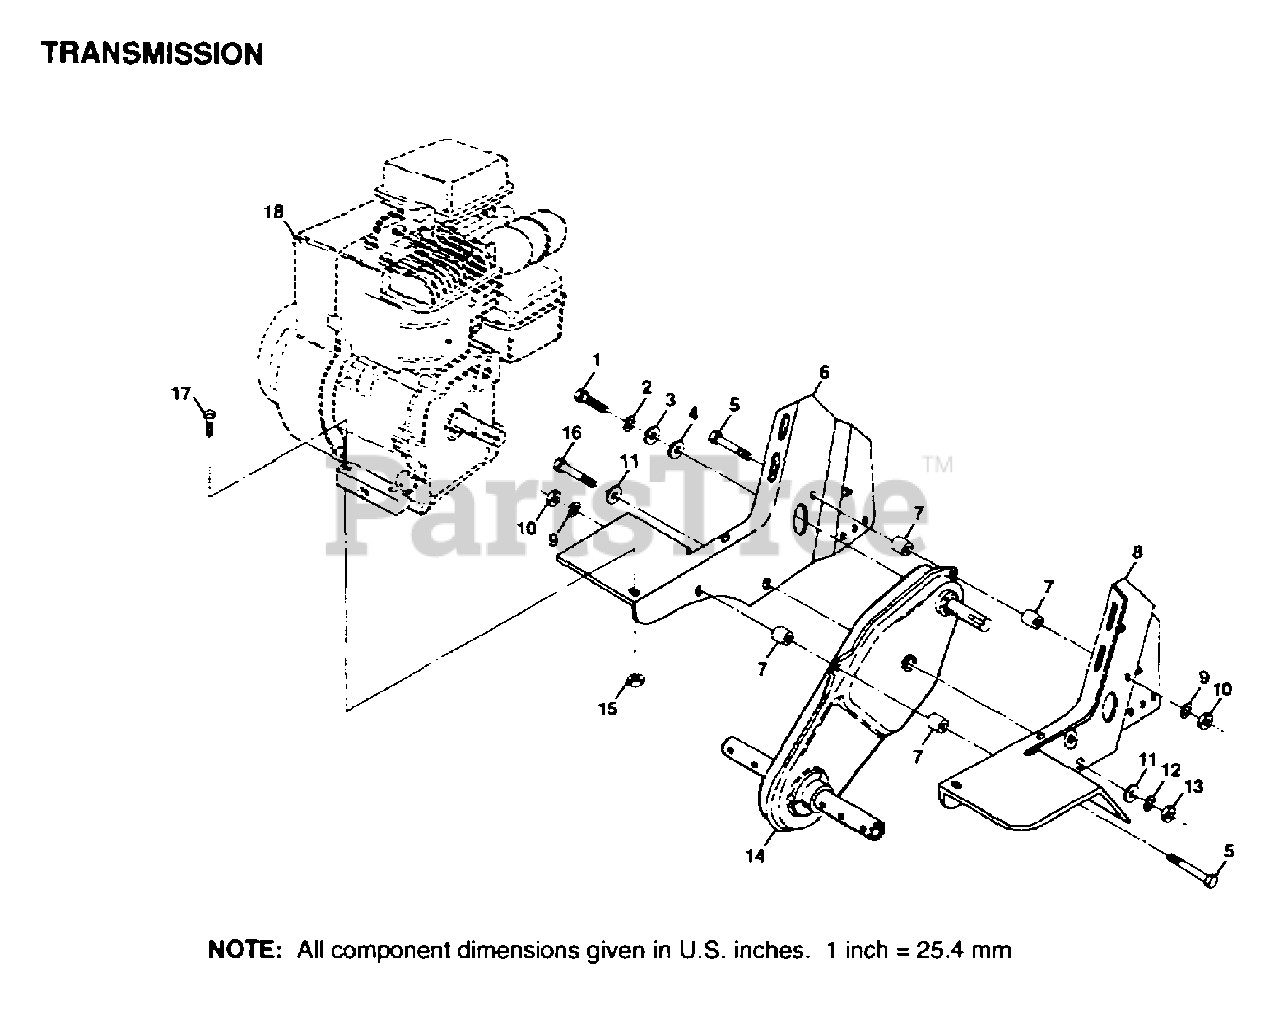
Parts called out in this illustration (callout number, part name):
1	BOLT
2	LOCKWASHER
3	WASHER
4	WASHER
6	"BRKT, ENG. RH"
7	SPLIT SPACER RT
9	LOCKWASHER
11	WASHER
12	LOCKWASHER
13	GRIPCO NUT
16	BOLT.3/8-24X3.75
17	BOLT.HEX.5/16-1.5
